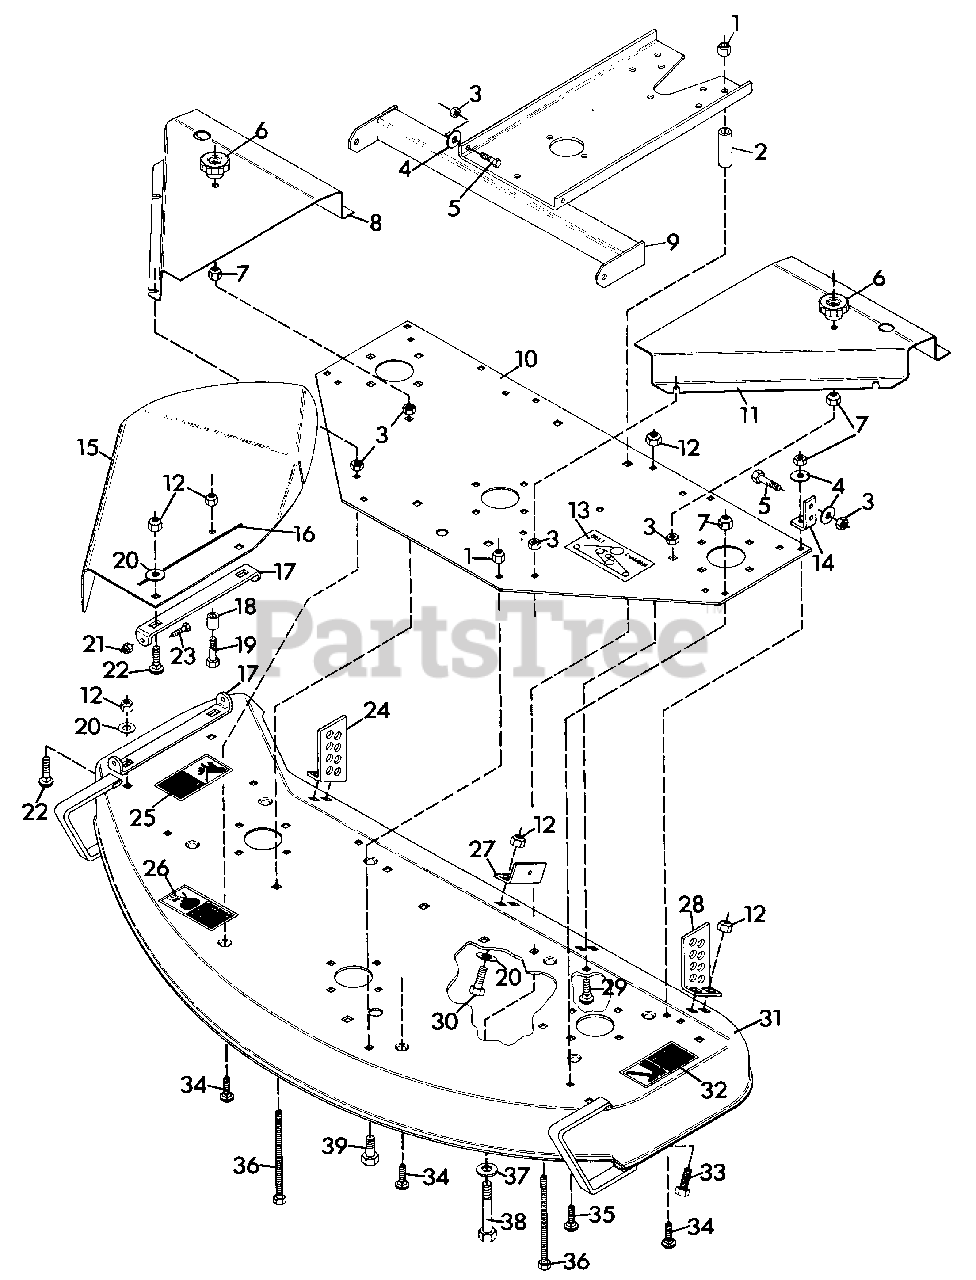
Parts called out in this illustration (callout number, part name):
1	Nut, Lock 1/2-13
2	Spacer, .510x.840x2.43
3	Nut, Jam 5/16-18 Hex
4	Washer, Flat .344x.688x.065
5	Bolt, Hex 5/16-18x1.25
6	Knob
7	Nut, Lock 5/16-18
8	Cover, Pulley R.H.
9	Weldment, Plate Support
10	Plate, Support
11	Cover, Pulley L.H.
12	Nut, Lock 3/8-16
13	Decal, Belt Installation
14	Bracket, Lift Pivot
15	Shield, Safety Extension
16	Stripe
17	Bracket, Chute
18	Stop, Chute
19	Bolt, Hex 3/8-16x1.50
20	Washer, Flat .406x.812x.065
21	Nut, Lock 1/4-20
22	Bolt, 3/8-16x1.00 Rd Hd Sq Nk
23	Bolt, Hex 1/4-20x.875
24	Plate, Rear Adjustment
25	Decal, Danger Hand
26	Decal, Warning Eye
27	Bracket, Lift
28	Plate, Rear Adjustment
29	Bolt, Carriage 3/8-16x.75
30	Bolt, Hex 3/8-16x1.00
31	Weldment, 50" Mower Deck
32	Decal, Danger Foot
33	Bolt, Hex 3/8-16x1.25
34	Bolt, Carriage 5/16-18x1.00
35	Bolt, Carriage 5/16-18x.75
36	Bolt, Hex 5/16-18x3.50
37	Washer, Flat .531x1.062x.095
38	Bolt, Hex 1/2-13x3.75
39	Bolt, Hex 1/2-13x1.25
